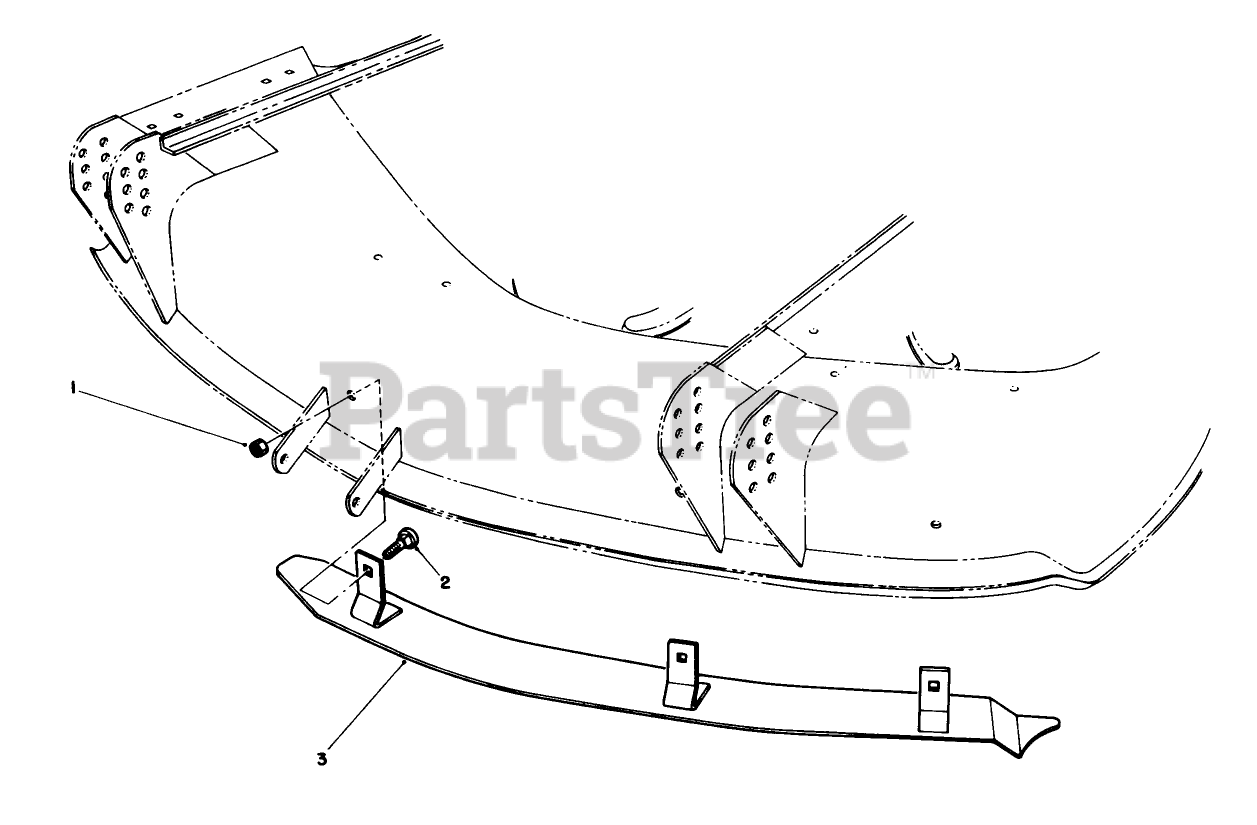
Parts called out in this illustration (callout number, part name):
1	NUT-LOCK, NI
2	SCREW-CARR
3	Baffle Assembly
